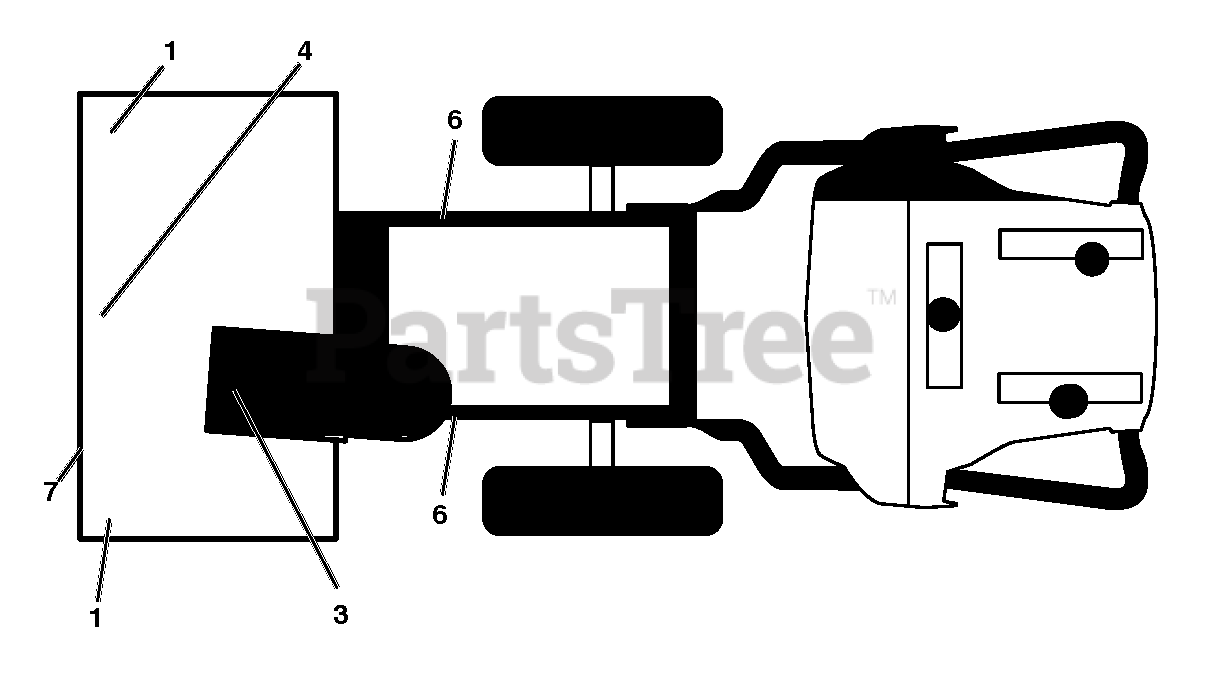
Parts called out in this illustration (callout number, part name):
1	DECAL.AUGER.SAFETY.
3	DECAL.CHUTE.SAFETY.EU/SC.17
4	DECAL.AUGER."
6	DECAL.BELT.GUARD.
7	DECAL SNOW BUCKET TRIM GRAPHIC
